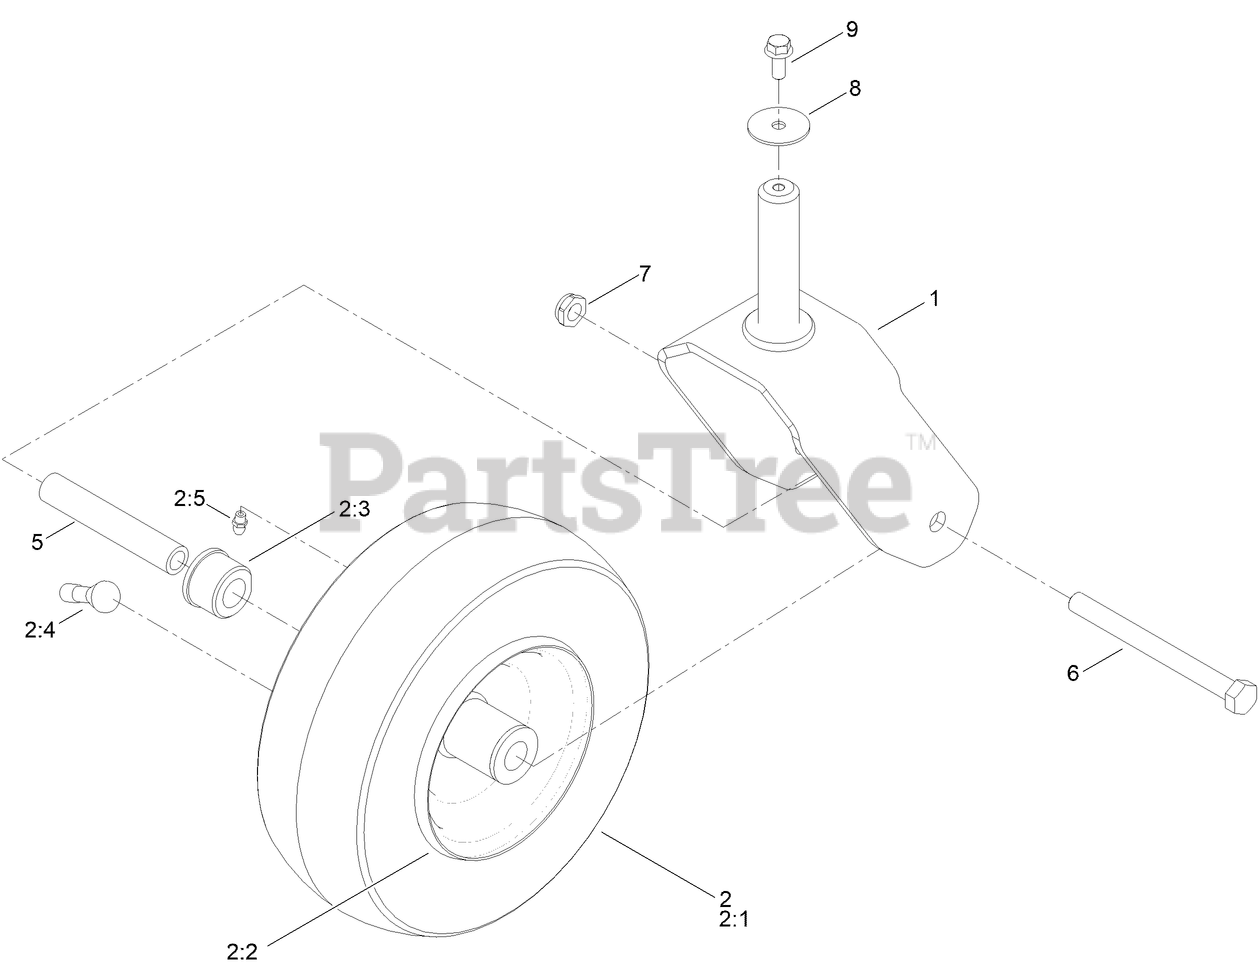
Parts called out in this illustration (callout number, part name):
1	FORK ASM
2	TIRE ASM
2:3	BUSHING-FLANGE
2:5	FITTING-GREASE
5	BUSHING-SPANNER
6	SCREW-HH
7	NUT-HEX
8	WASHER-FLAT
9	SCREW-HHF
